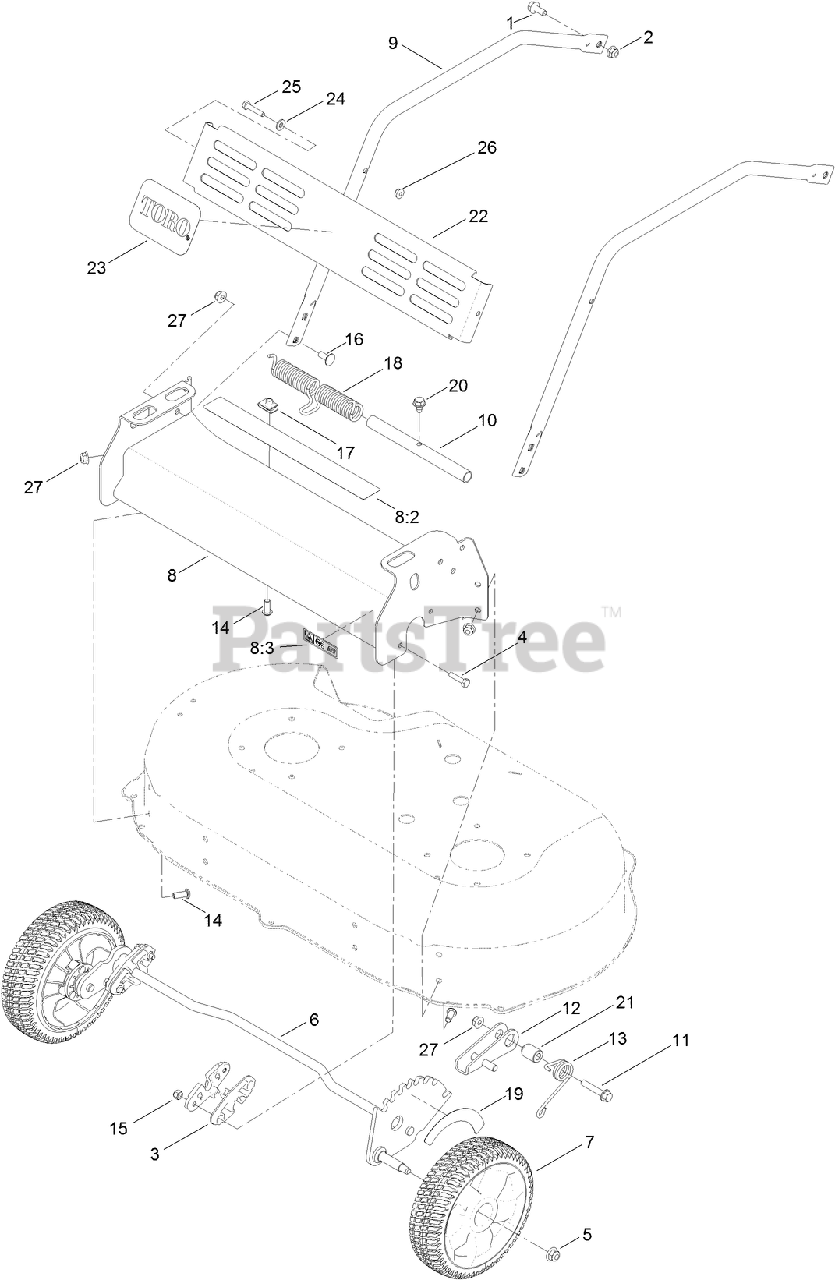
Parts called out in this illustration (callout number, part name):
1	SCREW-HHF
2	NUT-HF, NI
3	BUSHING-FRONT
4	SCREW-HH
5	NUT-HF, NI
6	AXLE-FRONT
7	8 INCH WHEEL AND RING ASM
8	FRONT BUMPER ASM
8:3	DECAL-WARNING
10	MANDRELL-SPRING
11	SCREW-HWH
12	LOCK-HEIGHT, ADJUSTMENT
13	SPRING-TORSION
14	SCREW-HSBH
15	NUT-LOCK, NI
16	SCREW-CARR
17	NUT-U
18	SPRING-TORSION
19	DECAL-HOC, FRONT
20	SCREW
21	SPACER
24	WASHER-FLAT
25	SCREW-HH
26	NUT-HF
27	NUT-HF, NI
